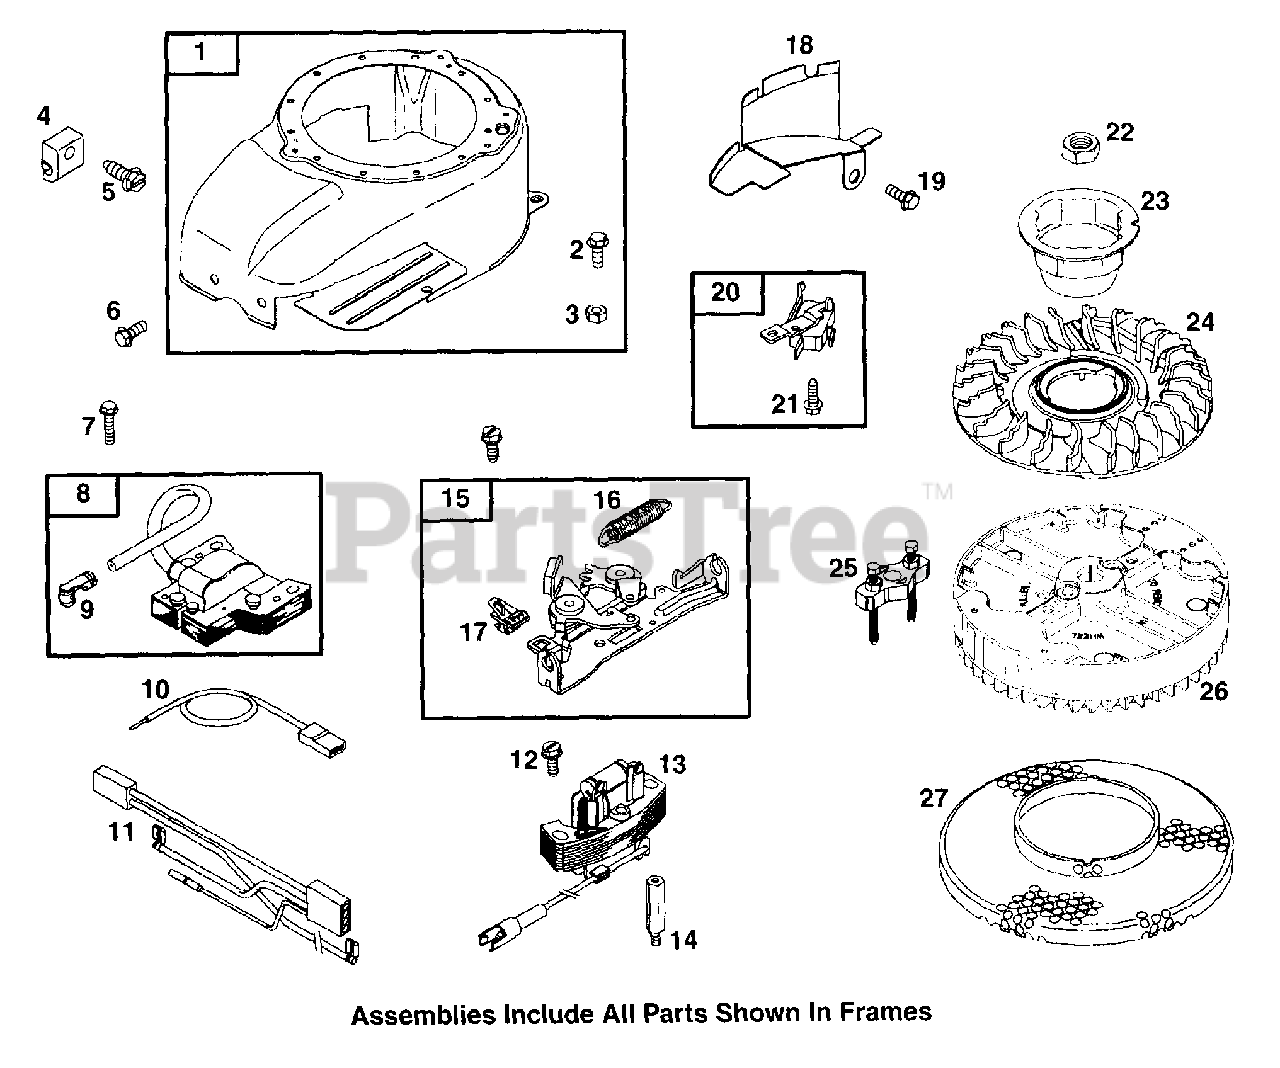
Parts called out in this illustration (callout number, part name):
1	Blower Housing
2	Hex Screw
3	Hex Screw
4	Casing Clamp
5	Slotted Hex Screw
6	Hex Screw
7	Hex Screw
8	Magneto Armature
9	Cable Terminal
10	Wiring Stop
11	Wiring Harness
12	Slotted Hex Screw
13	Alternator
14	Stud
15	Brake
16	Brake Spring
17	Stop Switch
18	Flywheel Guard
19	Hex Screw
20	Interlock Switch
21	Hex Screw
22	Flywheel Nut
23	Flywheel Cup
24	Flywheel Fan
25	Flywheel Puller
26	Flywheel
27	Rotating Screen
